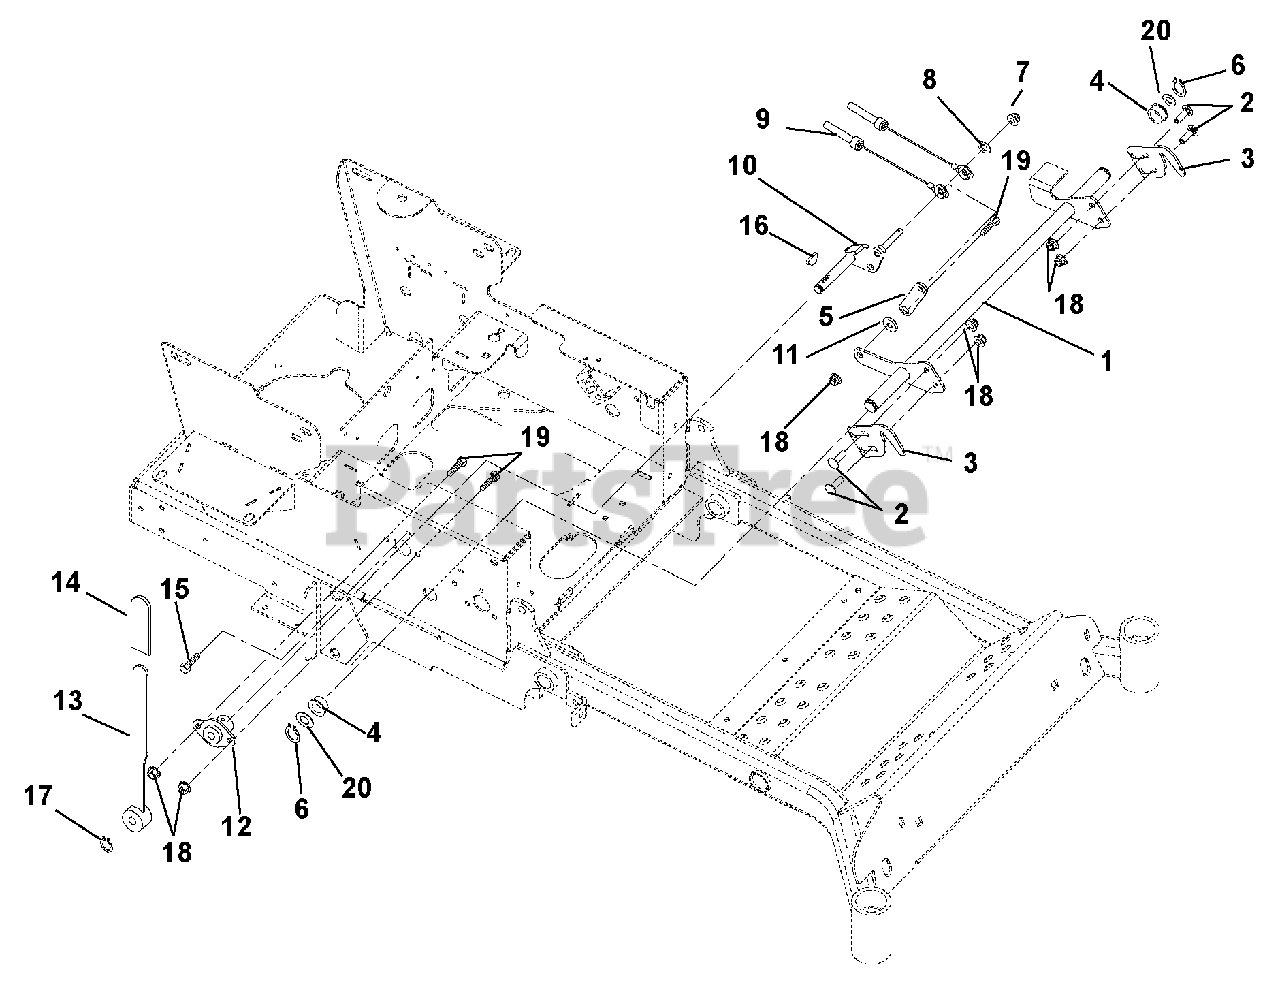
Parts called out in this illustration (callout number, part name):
1	Weldment, Neutral Lock Arm
2	Bolt, Round Head Square Neck .31-18 x 1.00 Grade 5
3	Neutral Lock Latch
4	Bushing, Flange .750 x 1.000 x .625 x 1.250
5	Plate, Neutral Interlock
6	Ring, Retaining, External .689 x .077
7	Nut, Push .312
8	Washer, Flat Steel .344 x .688 x .065
9	Cable, Brake Actuating
10	Weldment, Park Brake Arm
11	Bushing, Flange .325 x .499 x .26 x .88
12	Bushing, Flange
13	Weldment, Parking Brake Lever
14	Grip, Parking Brake
15	Screw, Tapping .38-16 x 1.00 Hex Washer Head
16	Key, Woodruff .13 x .63
17	Ring, Retaining External .50 x .05
18	Nut, Nyloc Flange 5/16-18
19	Bolt, Hex .31-18 x 1.00 Grade 5
20	Washer, Flat Steel .812 x 1.370 x .100
